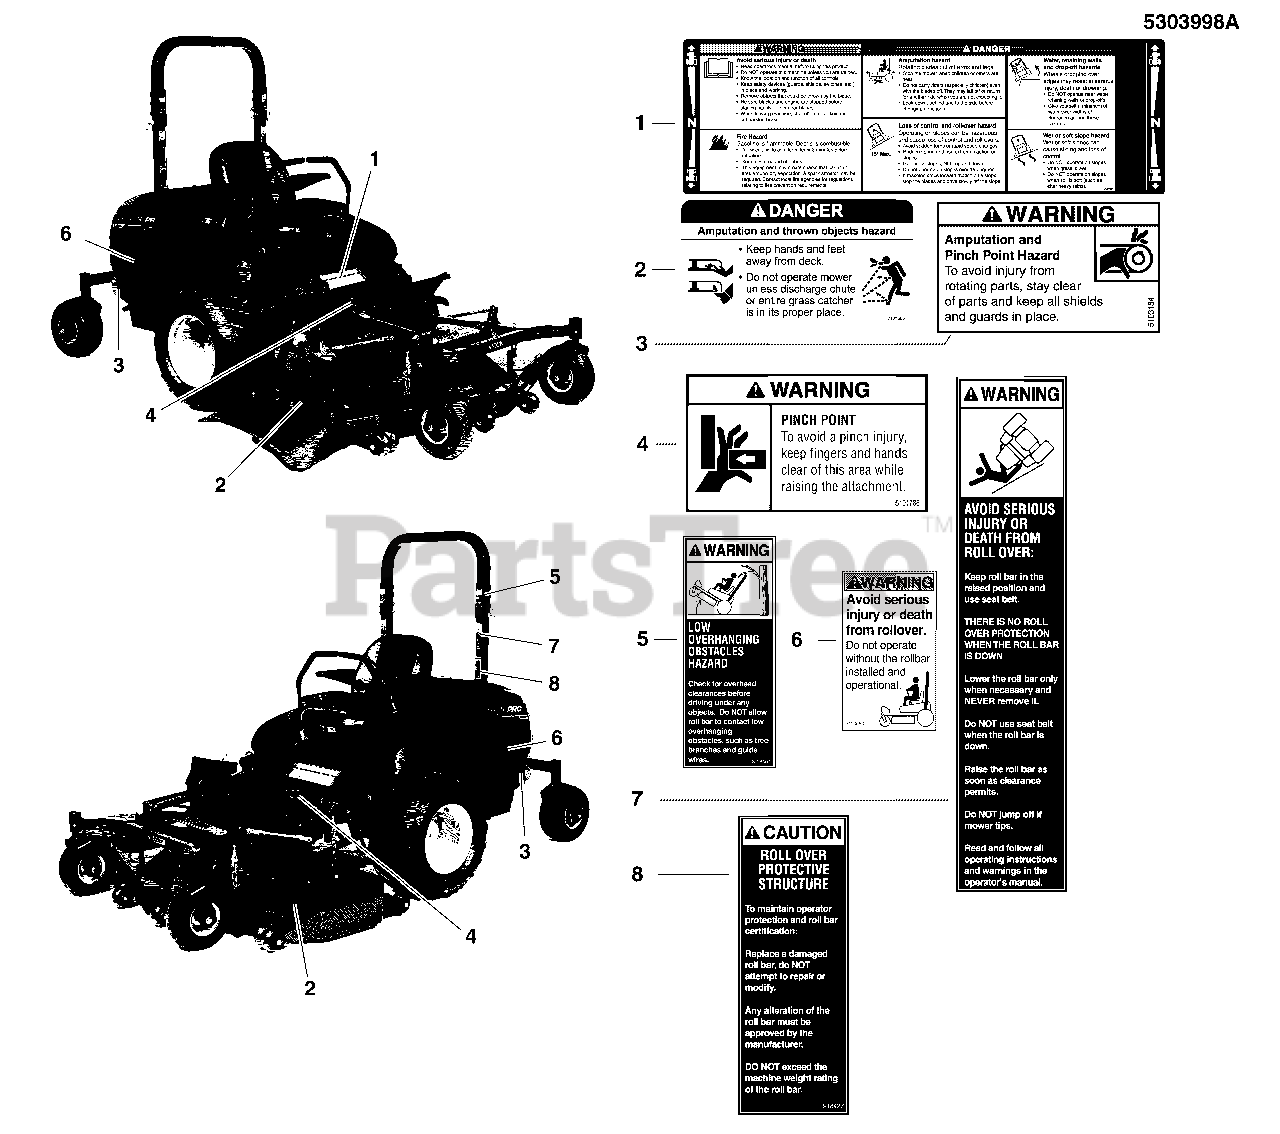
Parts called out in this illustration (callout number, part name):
1	DECAL ASSEMBLY, MAIN SAFETY, 800X (SV)
2	DECAL, DANGER DO NOT OPERATE W/O DEFLECT
3	DECAL, WARNING, HAND IN BELT, ENG
4	DECAL, PINCH POINT, S800X
5	DECAL, WARNING OVERHANG, ROPS
6	DECAL, WARNING, ROLL BAR
7	DECAL, WARNING, FLDG ROPS
8	DECAL, CAUTION, FLDG ROPS
